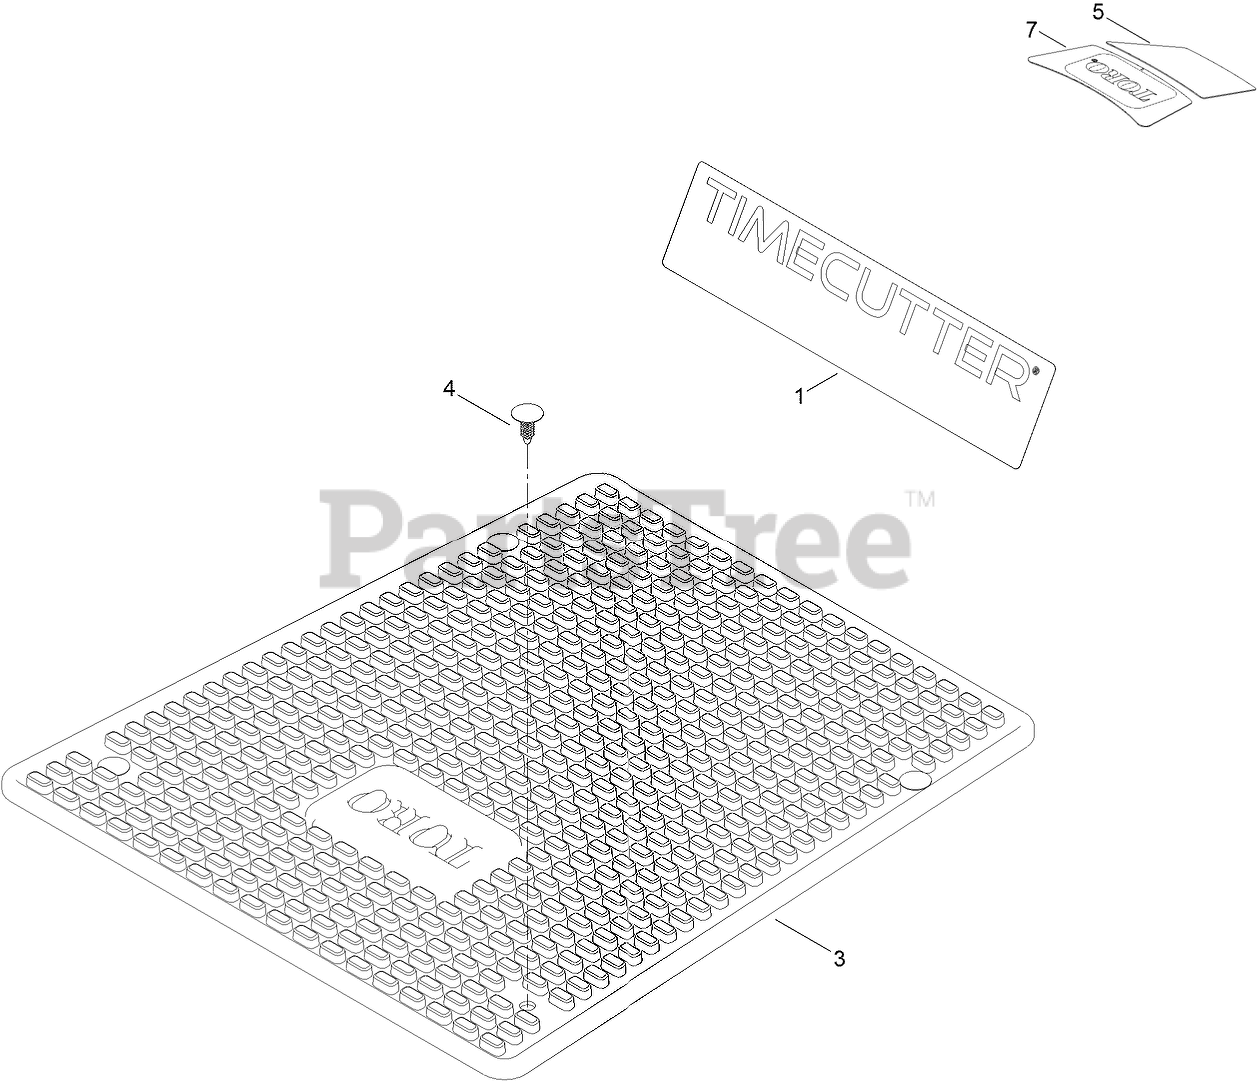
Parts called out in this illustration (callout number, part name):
1	DECAL-TIMECUTTER
3	MAT-FLOOR
4	PLUG-PLASTIC
5	DECAL-DISPLACEMENT, ENGINE
7	DECAL-ENGINE
